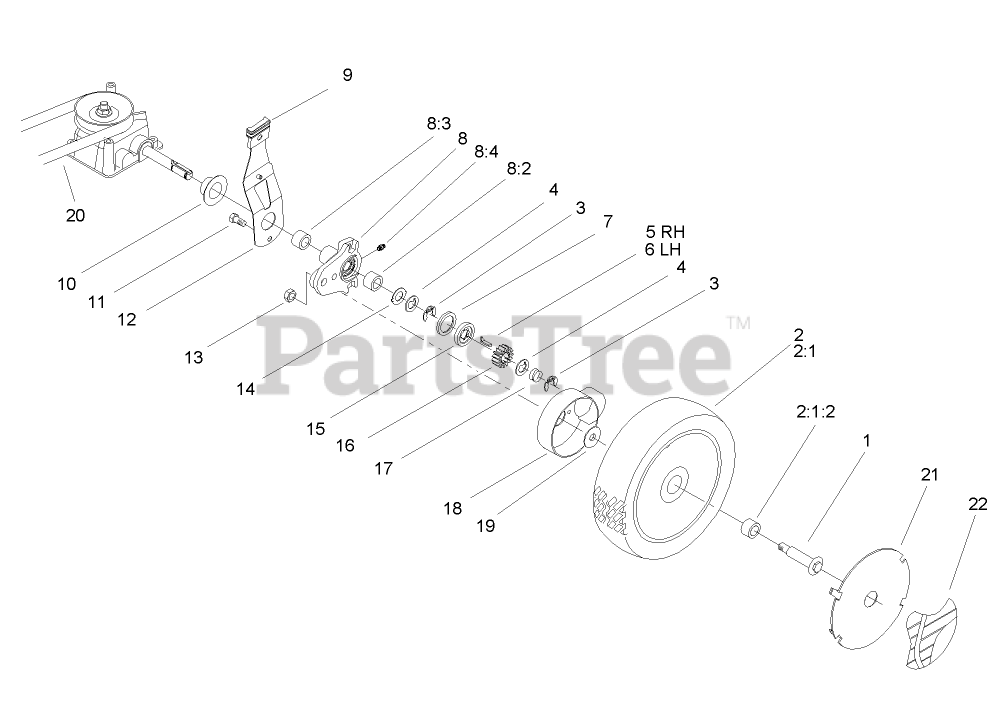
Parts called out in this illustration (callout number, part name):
1	BOLT-SHOULDER
2	WHEEL ASM
2:1	Wheel ASM
2:1:2	BUSHING
3	RING-RETAINING,CLIP
4	WASHER-THRUST, KEYED
5	KEY-ROCKING, RH
6	KEY-ROCKING, LH
7	RING-FRICTION
8	PIVOT ARM ASM
8:2	BUSHING
8:3	BUSHING
8:4	FITTING-GREASE
9	KNOB-ARM
10	CAP-END
11	SCREW-HWH
12	SPRING ARM ASM
13	LOCKNUT
14	WASHER-ARM, PIVOT
15	WASHER-CLUTCH
16	GEAR-PINION
17	SPRING-COMPRESSION
18	COVER-WHEEL
19	SPACER-COVER, WHEEL
20	BELT-V
21	COVER-WHEEL
22	LABEL-WHEEL, SMART
